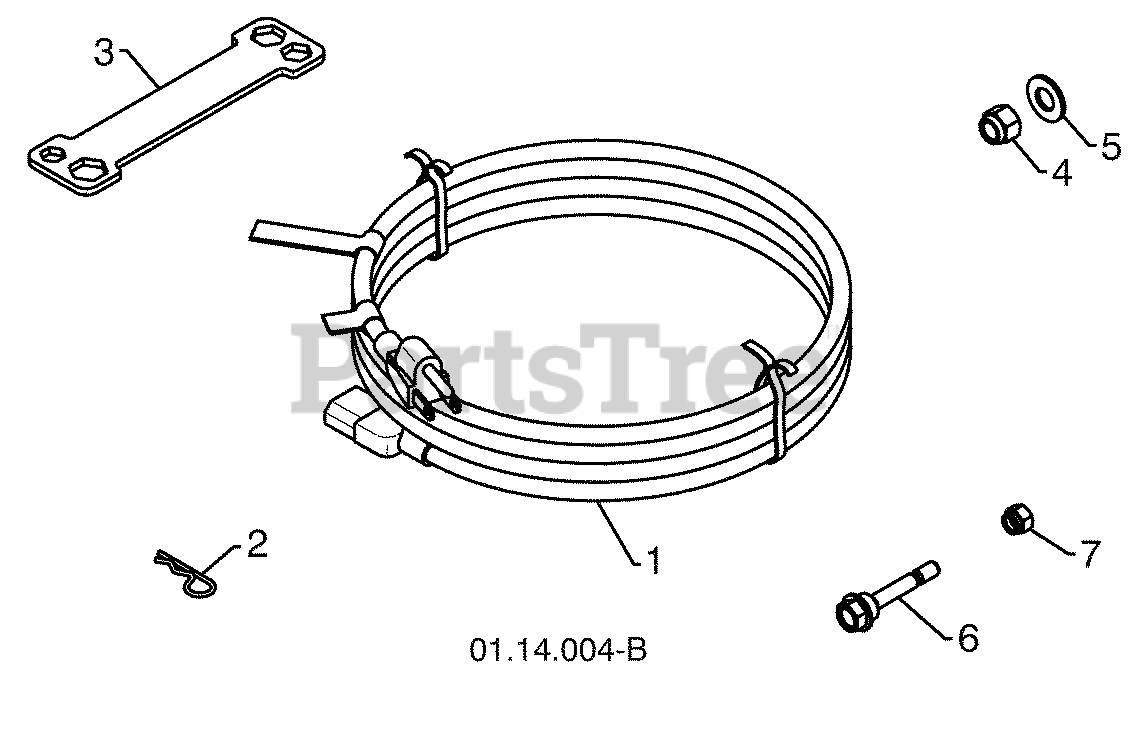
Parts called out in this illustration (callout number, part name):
1	CORD.ELECTRIC.10FT.120V.SNOW
2	SPRING RETAINER
3	WRENCH.SNOWTHROWER.ZINC.YZ
4	NUT
5	WASHER
6	BOLT.SHOULDER.SHEAR.1/4-20.
7	LOCKNUT.NYLOC.1/4-20
